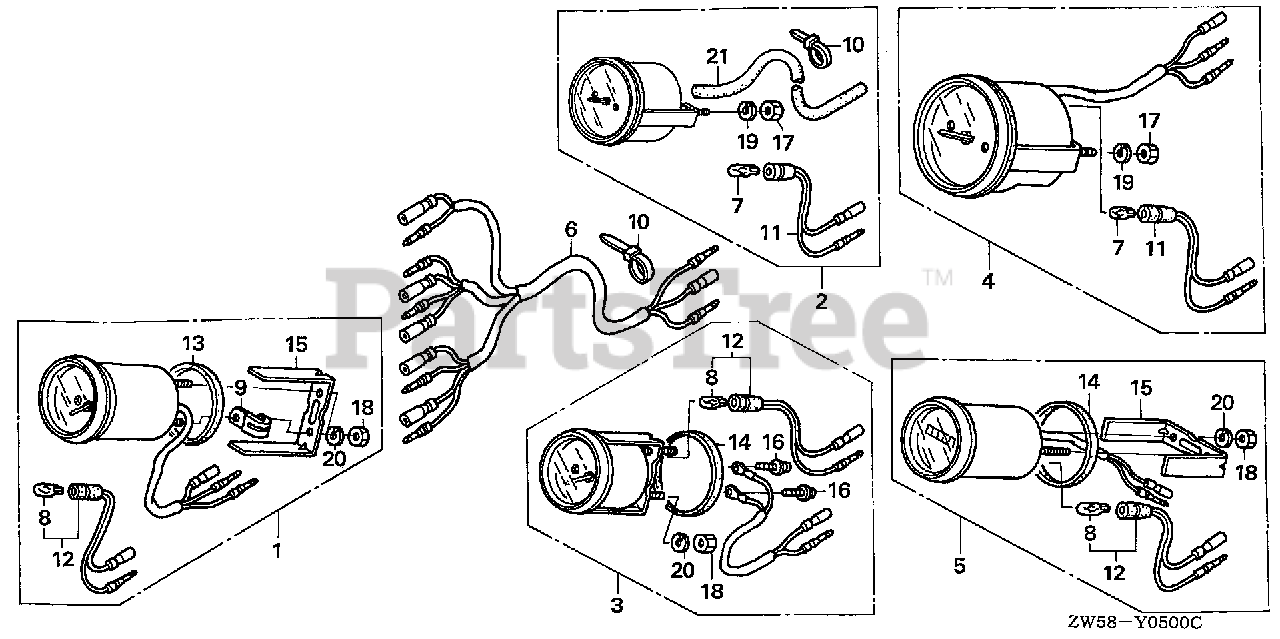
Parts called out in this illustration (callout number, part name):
1	METER KIT, TRIM (WHITE)
1	METER KIT, TRIM (B) (BLACK)
2	SPEEDOMETER KIT (WHITE) (NOT AVAILABLE)
2	SPEEDOMETER KIT (B) (NOT AVAILABLE)
3	METER KIT, VOLT (WHITE)
3	METER KIT, VOLT (B)
4	METER KIT, TACHO
4	METER KIT, TACHO (B)
5	METER KIT, HOUR (WHITE) (NA USE ALT:39700-ZW5-000ZA)
5	METER KIT, HOUR (B) (NA USE ALT:39700-ZW5-000ZA)
6	HARNESS ASSY., METER (B)
7	BULB, WEDGE BASE (T10) (12V 1.7W) (STANLEY)
8	BULB, WEDGE BASE (12V 1.7W)
9	CLAMP
10	BAND, SELF-LOCK
11	SOCKET
12	SOCKET
13	GASKET
14	GASKET
15	BRACKET
16	SCREW-WASHER (3X22)
17	NUT, HEX. (5MM)
18	NUT, HEX. (4MM)
19	WASHER, SPRING (5MM)
20	WASHER, SPRING (4MM)
21	TUBE, SPEED METER (4X7X8000)
